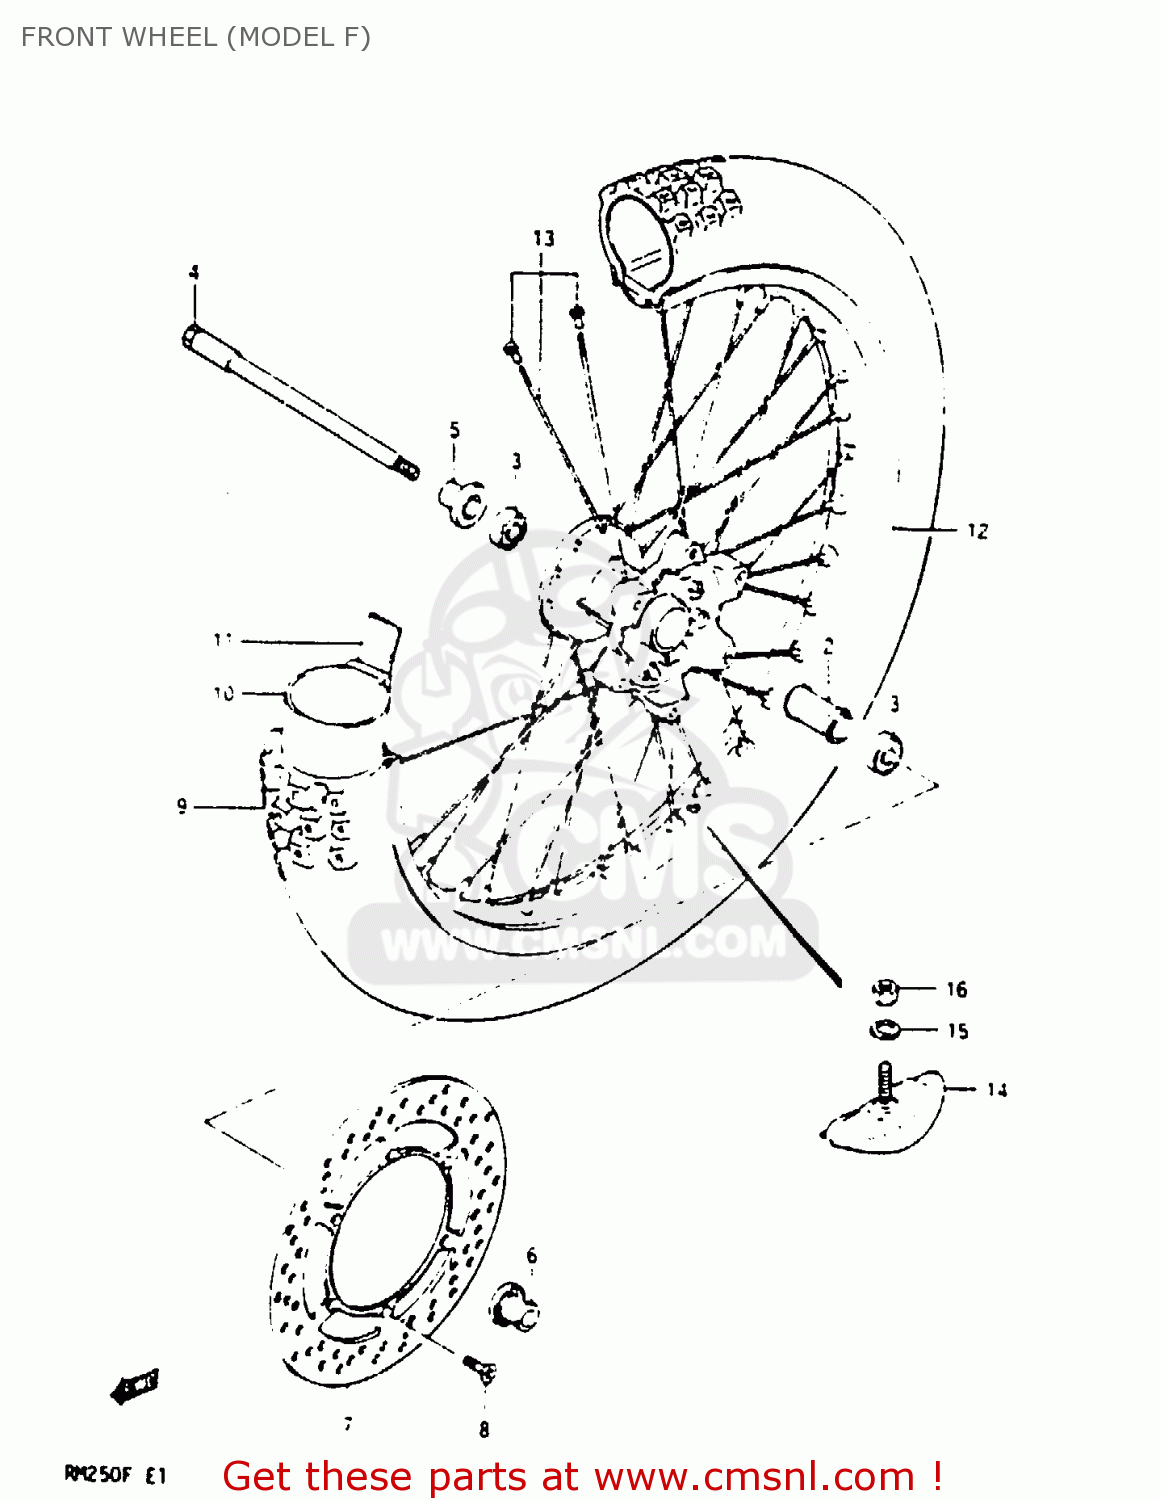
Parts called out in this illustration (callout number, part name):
1	HUB,FRONT
2	SPACER,FRONT HUB BEARING
3	BEARING
4	AXLE,FRONT
5	SPACER,FRONT AXLE,RIGHT
6	SPACER,FRONT AXLE,LEFT
7	DISC,BRAKE
8	SCREW
9	TIRE,FRONT
10	TUBE
11	PROTECTOR,WHEEL,INNER
12	RIM,FRONT WHEEL (1.60X21)(
13	SPOKE SET,FRONT
14	STOPPER,BEAD
15	WASHER
16	NUT
